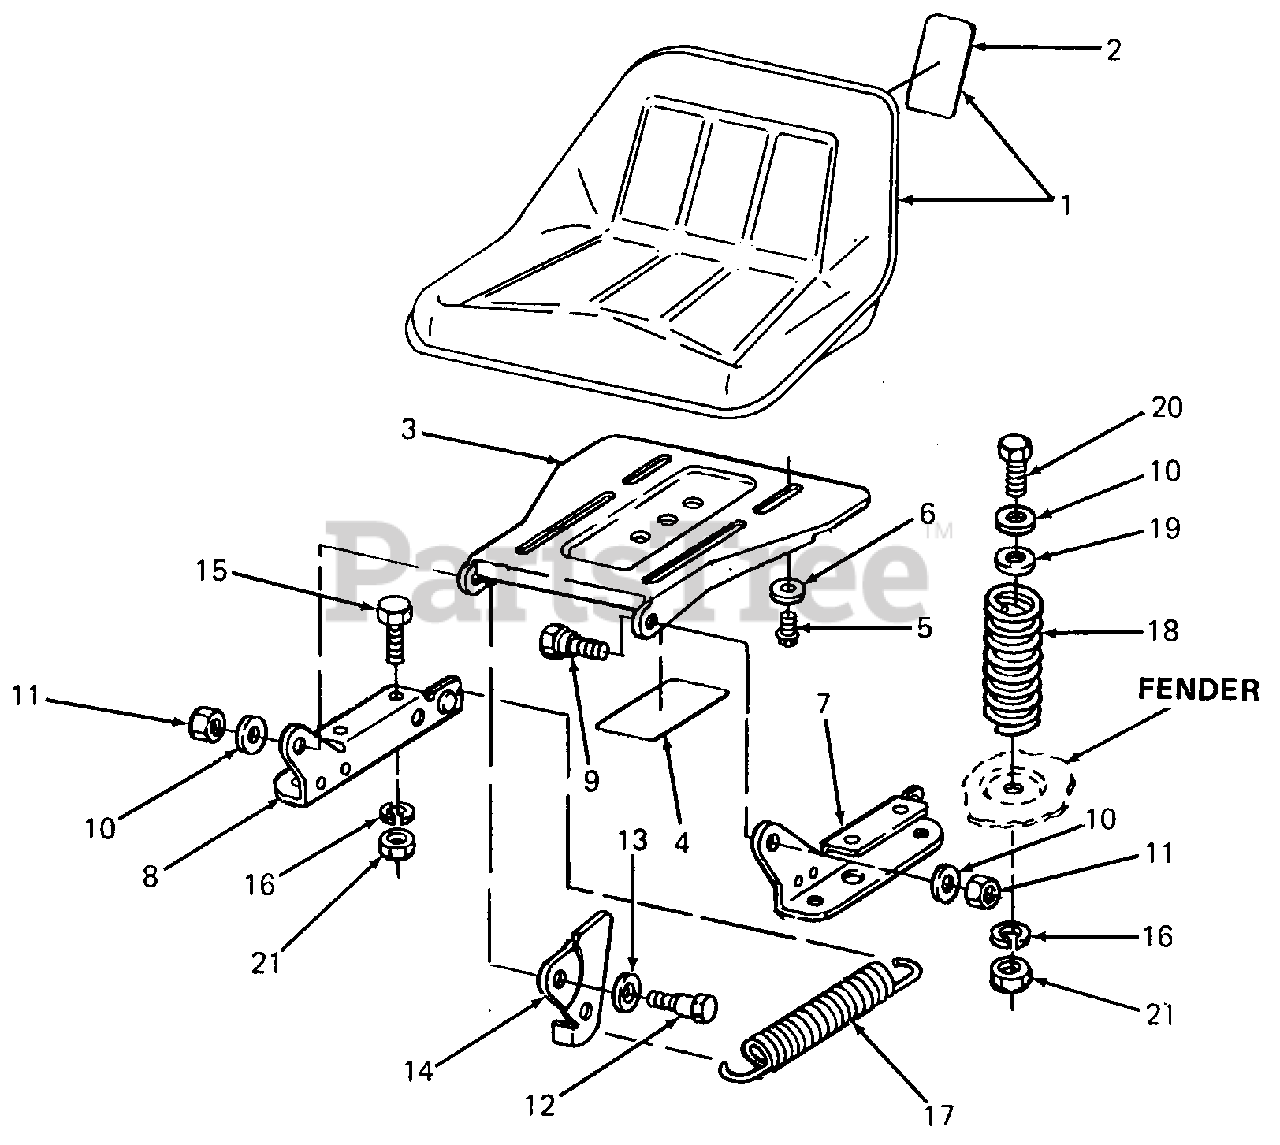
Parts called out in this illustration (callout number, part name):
1	Seat w/Graphic
2	Graphic, Seat
3	Bracket, Seat Pivot
4	Label, Booster Battery
5	Screw, Hex Wash Hd Tapp, 3/8-16 X .75 Lg
6	Washer, Bell, .400 X 1.13 X .030 Thk
7	Bracket, LH - Seat Pivot Support
10	Washer, Flat, .344 X .875 X .06 Thk
11	Nut, Hex Center Lock, 5/16-18 GR5
12	Screw, Shoulder, .437 Dia X .268
13	Washer, Spring, .445 X .75 X .017 Thk
14	Bracket, Seat Lift
15	Screw, Hex Cap, 5/16-18 X .75 Lg GR5
16	Washer, Lock, 5/16
17	Spring, Extension, .75 OD X 5.31 Lg
18	Spring, Compression
19	Bushing, .930 OD X .50 Lg
20	Screw, Hex Cap, 5/16-18 X 1.25 Lg
21	Nut, Hex, 5/16-18 GR5
